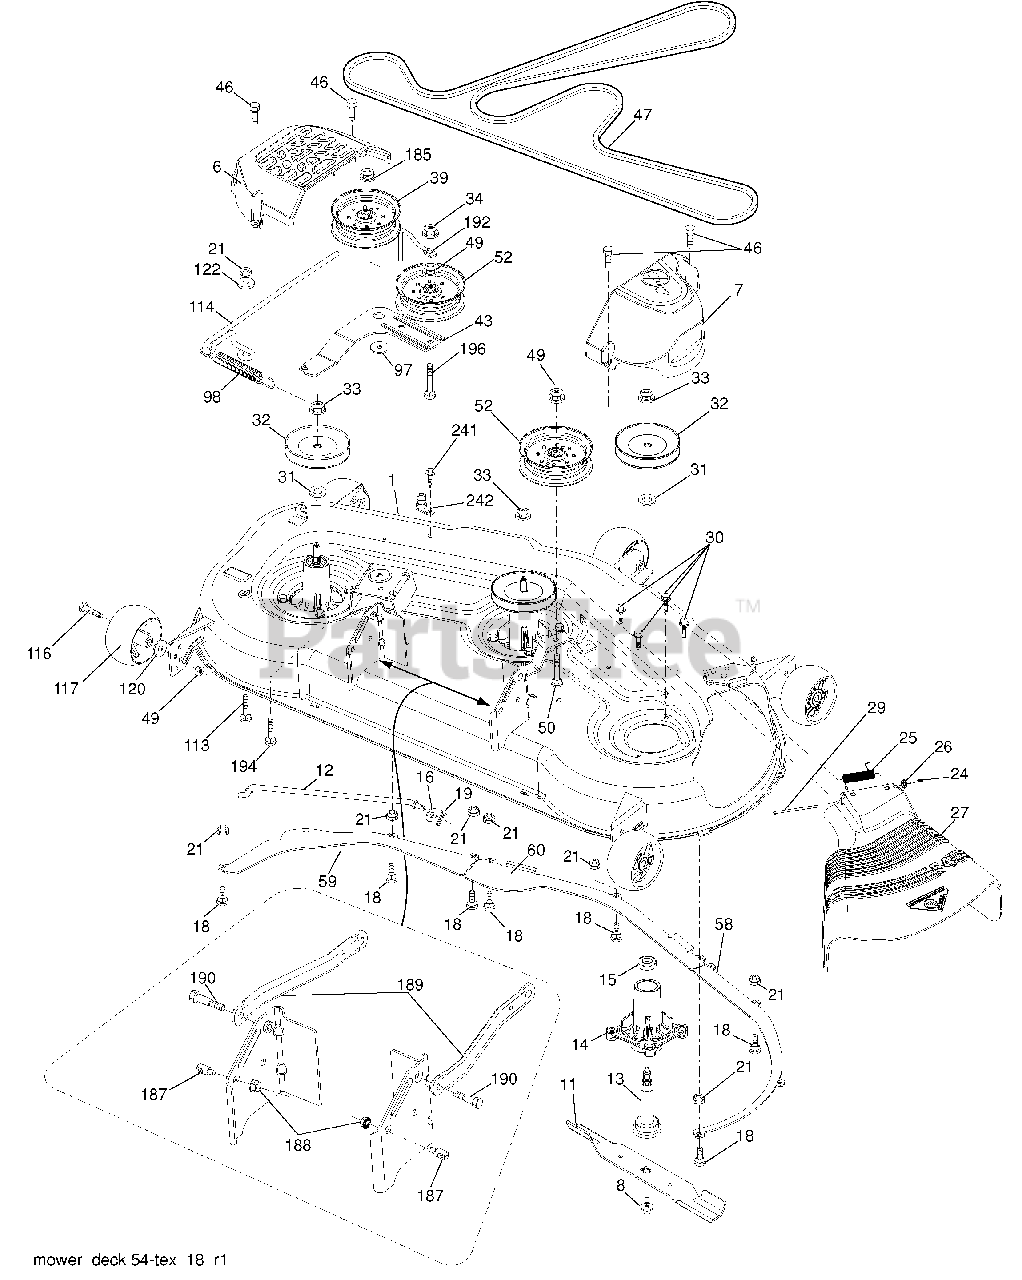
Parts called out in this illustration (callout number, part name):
1	Deck Weldment Mower
6	Cover Mandrel LH
7	Cover Mandrel RH
8	Bolt 7/16 Asm. Blade
11	Blade Bagging
11	Blade, 54" Mulching
12	Rod Anti-Sway
13	Shaft Asm. w/Lower Bearing
14	Housing, Mandrel
15	Bearing, Ball, Mandrel
16	Washer 13/32 x 13/16 x 12 Ga.
18	Bolt Carr. 5/16-18 x 5/8
19	Pin Cotter 5/16 Bow Tie Lock
21	Nut, Crownlock 5/16-18 unc
24	Cap Sleeve
25	Spring, Torsion
26	Nut, Push
27	Deflector Shield
29	Rod, Hinge
30	Screw, Thdroll Washer Head
31	Washer, Spacer Mower Vented
32	Pulley, Mandrel
33	Nut, Flg. Top Lock
34	Nut Crownlock 3/8-16 unc
39	Pulley, Idler, Stationary
43	Arm, Idler
46	Screw, Thdroll. 1/4-20 x 5/8
47	V-Belt, Mower
49	Nut, Lock Flg. 3/8-16 unc
50	Bolt Rdhd Sqnk 3/8-16 unc x 2
52	Pulley Idler 4.50
58	Baffle Right
59	Baffle Left
60	Baffle Center
97	Washer Hardened
98	Spring Drive
113	Bolt Rdhd Sqnk 5/16-18 x 3/4
114	Rod Tension Relief
116	Bolt, Shoulder
117	Gauge Wheel
120	Washer 13/32 x 1-1/4 x 12 Ga.
122	Bushing Tension Relief
185	Nut Lock Flange 7/16-14 Gr. 5
187	Stud Fastener w/"D" Anti-Rotation
188	Nut Lock Hex Flange 5/16-18
189	Arm Susp. Mower Rear
190	Bolt Shoulder
192	Keeper Belt Idler
194	Bolt Carr Sqnk 3/8-16 x 2-1/4
196	Bolt Rdhd 3/8-16 unc x 2-3/4 Gr. 5
241	Screw TT #10-32.5 3/8 Flange
242	Port Washout
242	Coupling Quick Disconnect
242	Mandrel Asm. Service
242	Replacement Mower, Complete
